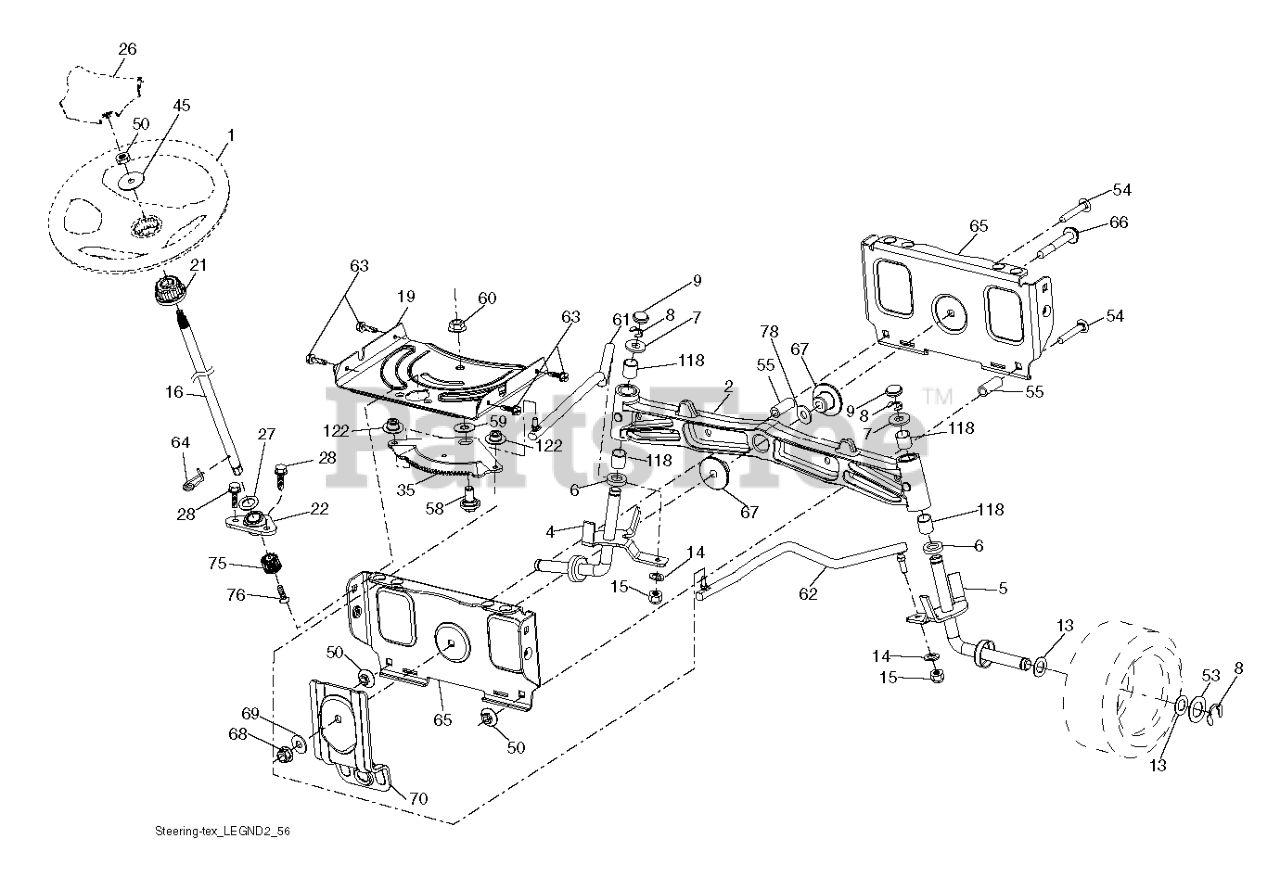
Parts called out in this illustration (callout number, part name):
1	WHEEL.STEER.HUSQ.SR.498.OVMLD
2	AXLE.SVC.ASM CAST IRON.TEX
4	SPINDLE.ASM.LH
5	SPINDLE.ASM.RH
6	THRUST WASHER
9	CAP.SPINDLE.BLACK
14	SLW 3/8 STD
15	NUT CROWNLOCK 3/8-24
16	SHAFT.STEER.2HIGH.SPLND.PLATED
19	PLATE.STEER.DDL.NLT/NG
21	ADAPTER.WHEEL.STEER.SPLND.ALUM
22	BEARING.SUBASM.SHAFT.STEER.LOW
26	INSERT.CAP.WHL.STRG.HUSQ.PREM
28	SCREW, 3/8-16X3/4
35	GEAR.SECTOR.PLATE.DDL.
45	WASHER.3/8ID.2-3/8OD.12GA.PLTD
50	NUT LOCK FLG 3/8-16 UNC
53	WASHER.HARDENED
55	SPACER.BRACE.AXLE
58	BOLT.SHOULDER.SECTOR.P
59	WASHER.THURST.SECTOR.S
60	NUT FLANGE LOCK 5/8-11
61	LINK.ASM.DRAG.ADJUST.LH.PLATED
62	LINK.ASM.DRAG.ADJUST.RH.PLATED
63	SCREW
64	RETAINER.CLIP.SPRING.S
65	BRACE.AXLE.FRONT.NLT/N
66	BOLT HEX FGHD 7/16-14 X 3 SERR
67	BUSHING.PM.FRONT AXLE
68	NUT.LOCK.FLANGE.7/16
69	WASHER.1.5X.505X.118
70	BRACKET.FRT.DECK.SUSP.RR.MT431
75	PINION.ZINC PLATED
76	SCREW HEAD SOCKET LRVB
78	THRUST WASHER
118	BUSHING, AXLE CAST
122	CAP.GEAR.SECTOR.TEX
